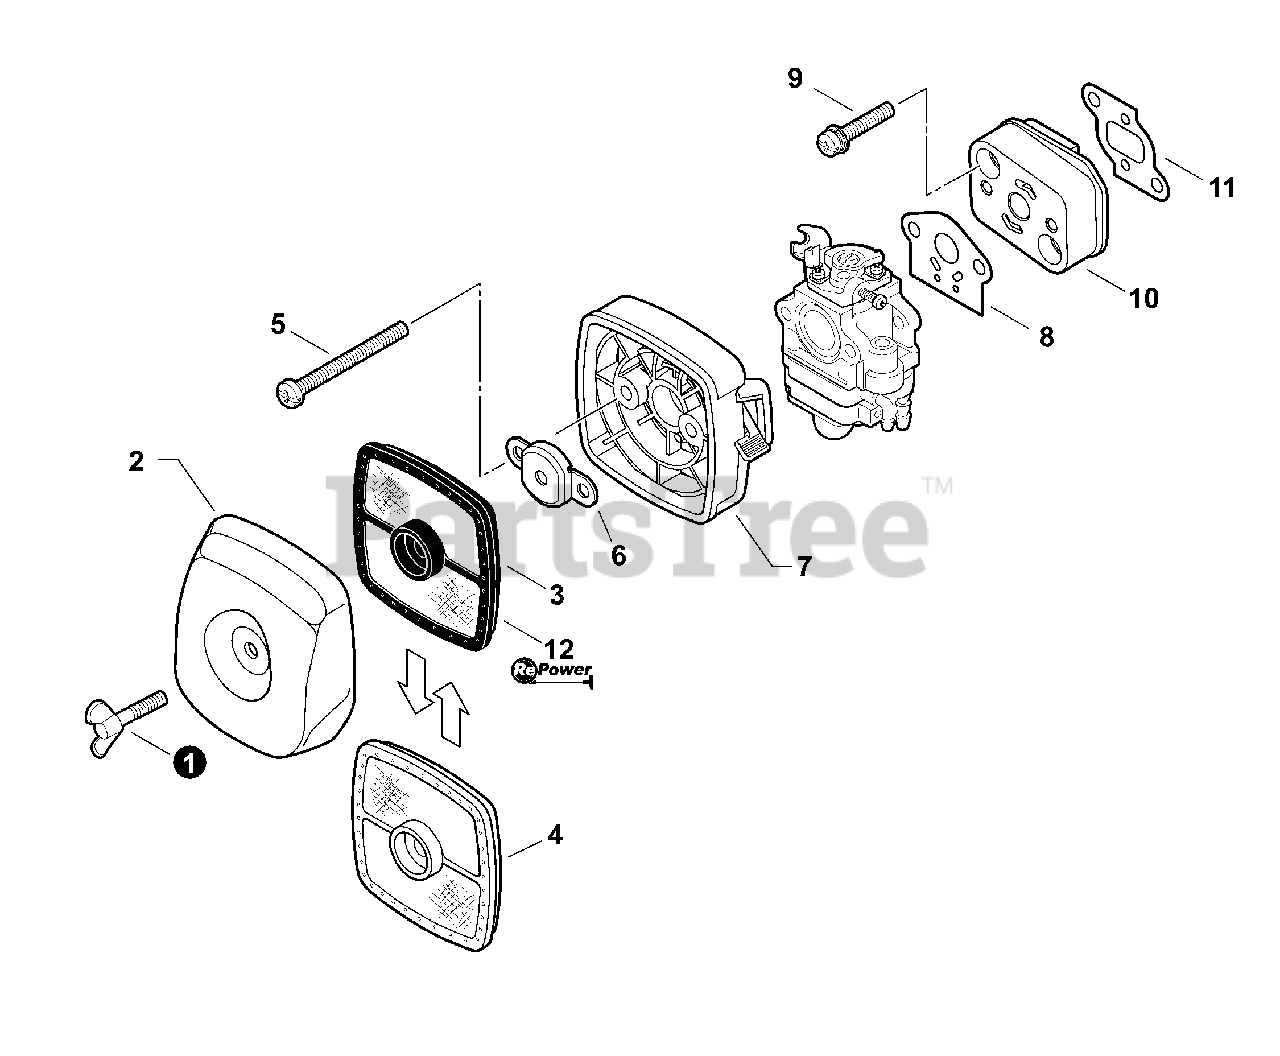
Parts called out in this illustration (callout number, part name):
1	BOLT, WING 5×20
2	COVER, AIR FILTER - BLACK
3	FILTER, AIR - DOUBLE LAYER
4	FILTER, AIR - SINGLE LAYER
5	SCREW 5×60
6	PLATE, PREVENT
7	CASE, AIR FILTER - BLACK
8	GASKET, CARBURETOR
9	BOLT 5×25
10	INSULATOR, INTAKE
11	GASKET, INTAKE
12	TUNE-UP KIT - REPOWER
12	FILTER KIT - REPOWER
